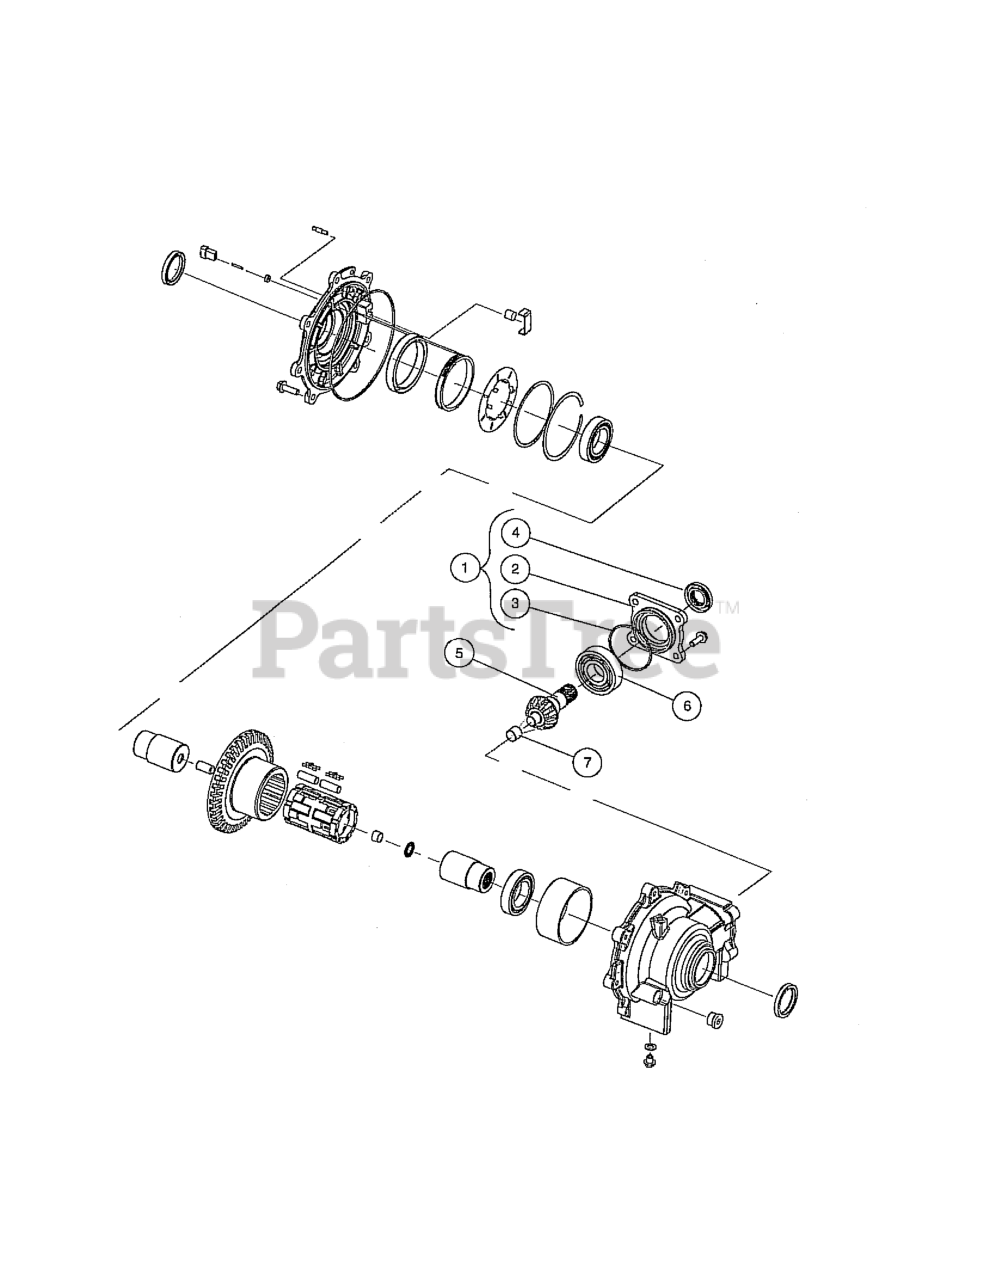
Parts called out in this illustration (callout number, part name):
1	KIT, ASSY, INPUT COVER PLATE
2	COVER, INPUT, MACHINED
5	SHAFT, PINION, MACHINED
6	BEARING, DGBR, 6306-C3
